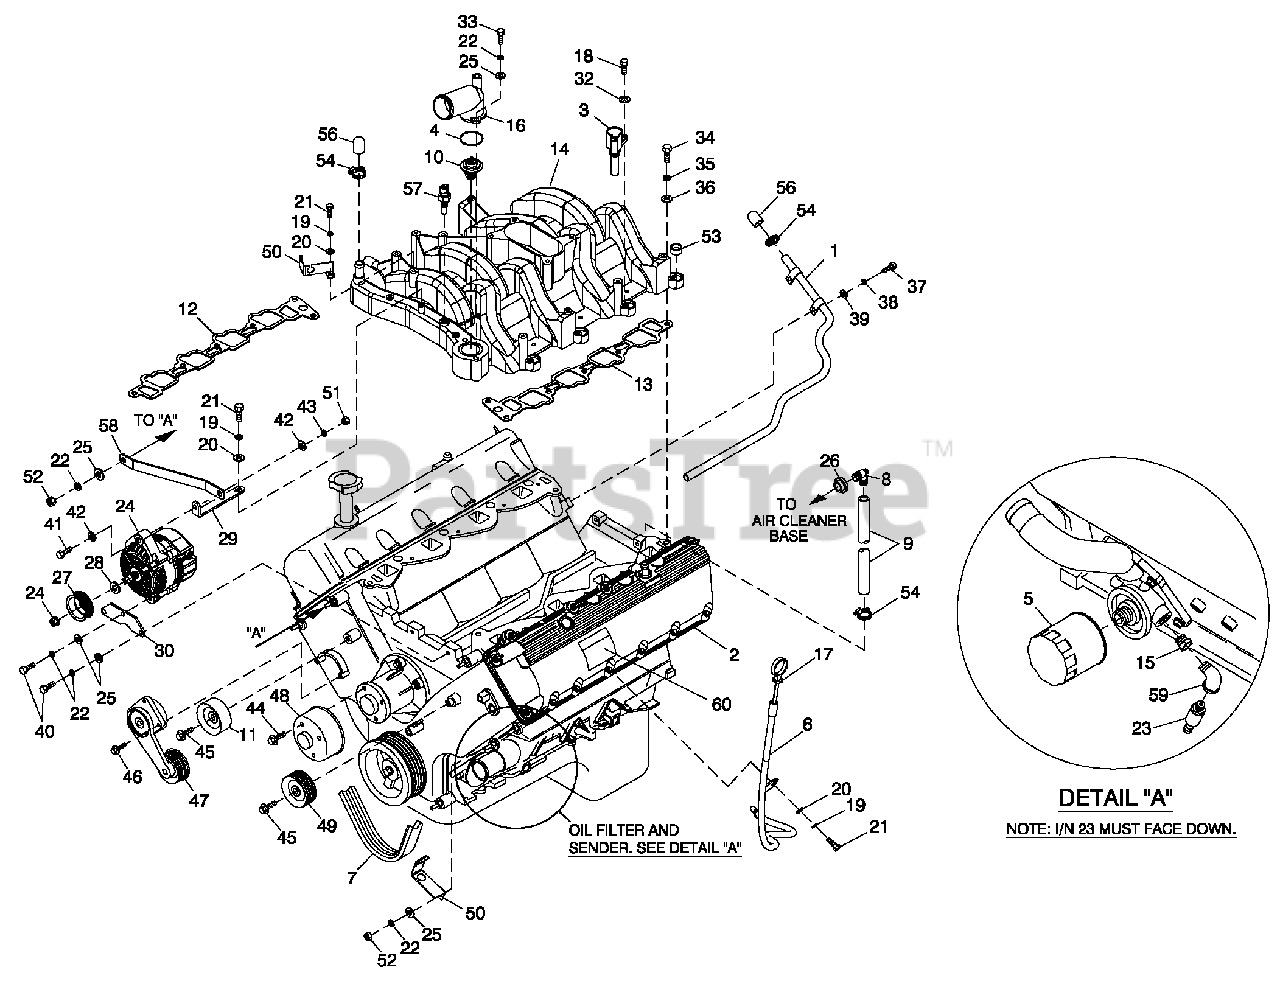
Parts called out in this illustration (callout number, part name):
1	TUBE HEATER WATER
2	ENGINE 5.4L FORD
3	IGNITION COIL ASSY FORD
4	GASKET THERMOSTAT HOUSING FORD
5	OIL FILTER FORD V-10 ENGINE
6	TUBE OIL LEVEL INDICATOR FORD
7	BELT SERPENTINE 65.0" (1800 RPM)
8	BARBED EL 90 3/4 PLASTIC
9	HOSE 3/4 ID SAE-30R2 (16.75"LG)
10	THERMOSTAT ASSY FORD
11	PULLEY FAN BELT FORD
12	GASKET INTAKE MANIFOLD RIGHT
13	GASKET INTAKE MANIFOLD LEFT
14	INTAKE MANIFOLD 5.4L (PLASTIC)
15	BSHG RDCRHEX1/4 TO 1/8
16	CONNECTION WATER OUTLET FORD
17	REWORK DIPSTICK 5.4L 27.75"
18	SCREW HHC M5-0.8X 25 G8.8
19	WASHER LOCK M6-1/4
20	WASHER FLAT 1/4 ZINC
21	SCREW HHC M6-1.0X 20 G8.8
22	WASHER LOCK M8-5/16
23	SENDER OIL PRESSURE 1/8"NPT
24	ALTERNATOR DC W/OUT PULLEY
25	WASHER FLAT 5/16 ZINC
26	GROMMET
27	PULLEY 80 OD DC ALTERNATOR (1800RPM)
28	SPACER DC ALTERNATOR PULLEY
29	BRKT DC ALTERNATOR UPPER
30	BRKT DC ALTERNATOR LOWER
32	WASHER FLAT M5
33	SCREW HHC M8-1.25X 90 G8.8
34	SCREW HHC M8-1.25X 50 G8.8
35	WASHER LOCK M8-5/16
36	WASHER FLAT 5/16-M8 ZINC
37	SCREW HHCM10-1.5X20 G8.8
38	WASHER LOCK M10
39	WASHER FLAT 3/8-M10 ZINC
40	SCREW HHC M8-1.25X 20 G8.8
41	SCREW HHC M10-1.5 X 45 G8.8 FT
42	WASHER FLAT 3/8-M10 ZINC
43	WASHER LOCK M10
44	SCREW WP PULLEY M8-1.25X 19
45	BOLT HEX FL HD M8-1.25X 28
46	BOLT HEX FL HD M8-1.25X 31
47	TENSIONER ENG. AUTOMATIC BELT
48	PULLEY WATER PUMP FORD (1800RPM)
49	PULLEY GROOVED ENGINE IDLER
50	BRACKET SIGNAL CONDITIONER
51	NUT HEX M10-1.5 G8YEL CHR
52	NUT HEX M8-1.25 G8YEL CHR
53	PLUG EXPANSION 14 OD
54	CLAMP HOSE#10.56-1.06
56	CAP RUBBER
57	TEMPERATURE SENDER, DELPHI
58	BRACKET DC ALT STABILIZER
59	ELBOW 90D STREET 1/8
60	DECAL EPA STATIONARY EMERGENCY
